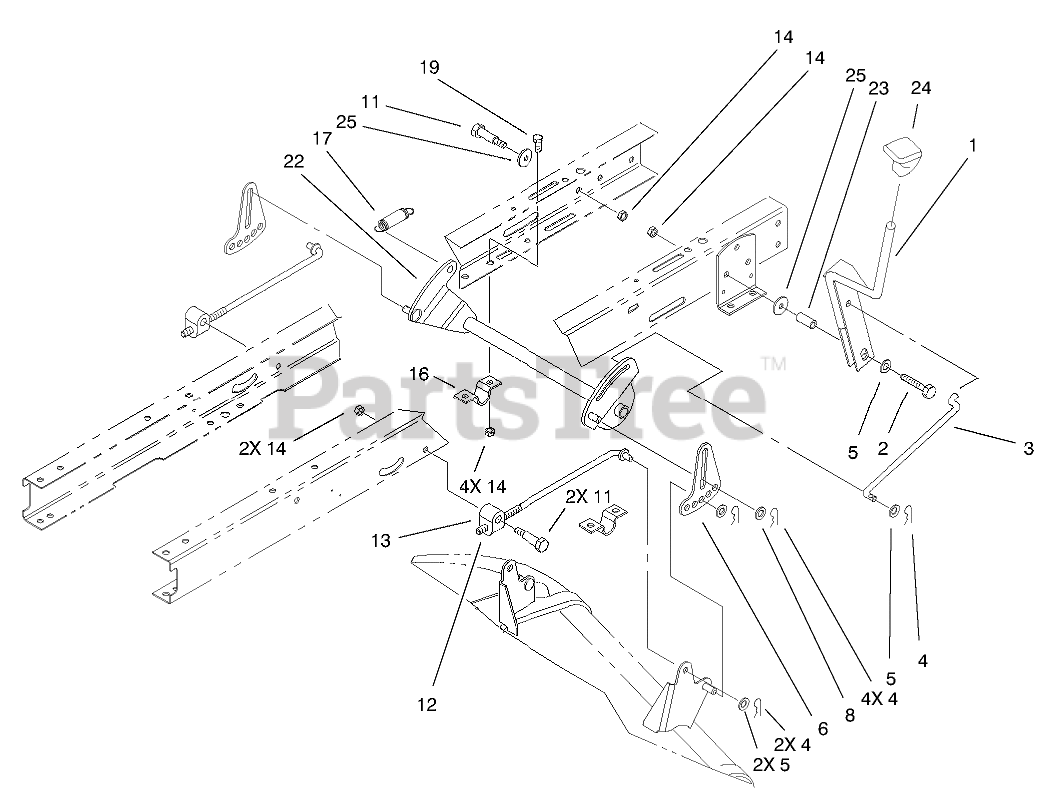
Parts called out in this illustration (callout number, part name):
1	HOC LEVER ASM
2	SCREW-HH
3	LINK-HOC
4	PIN-COTTER
5	WASHER-FLAT
6	LINK-ADJUSTING, HOC
8	WASHER-HARDENED
11	SCREW-SHOULDER, HH
12	ROD-HANGER, REAR
13	TRUNNION-HOC
14	NUT-LOCK, NI
16	CLAMP-PIVOT, HOC
17	SPRING-EXTENSION
19	SCREW-HH
22	PIVOT ASM
23	SPACER
24	KNOB-SHIFT
25	WASHER-PIVOT
